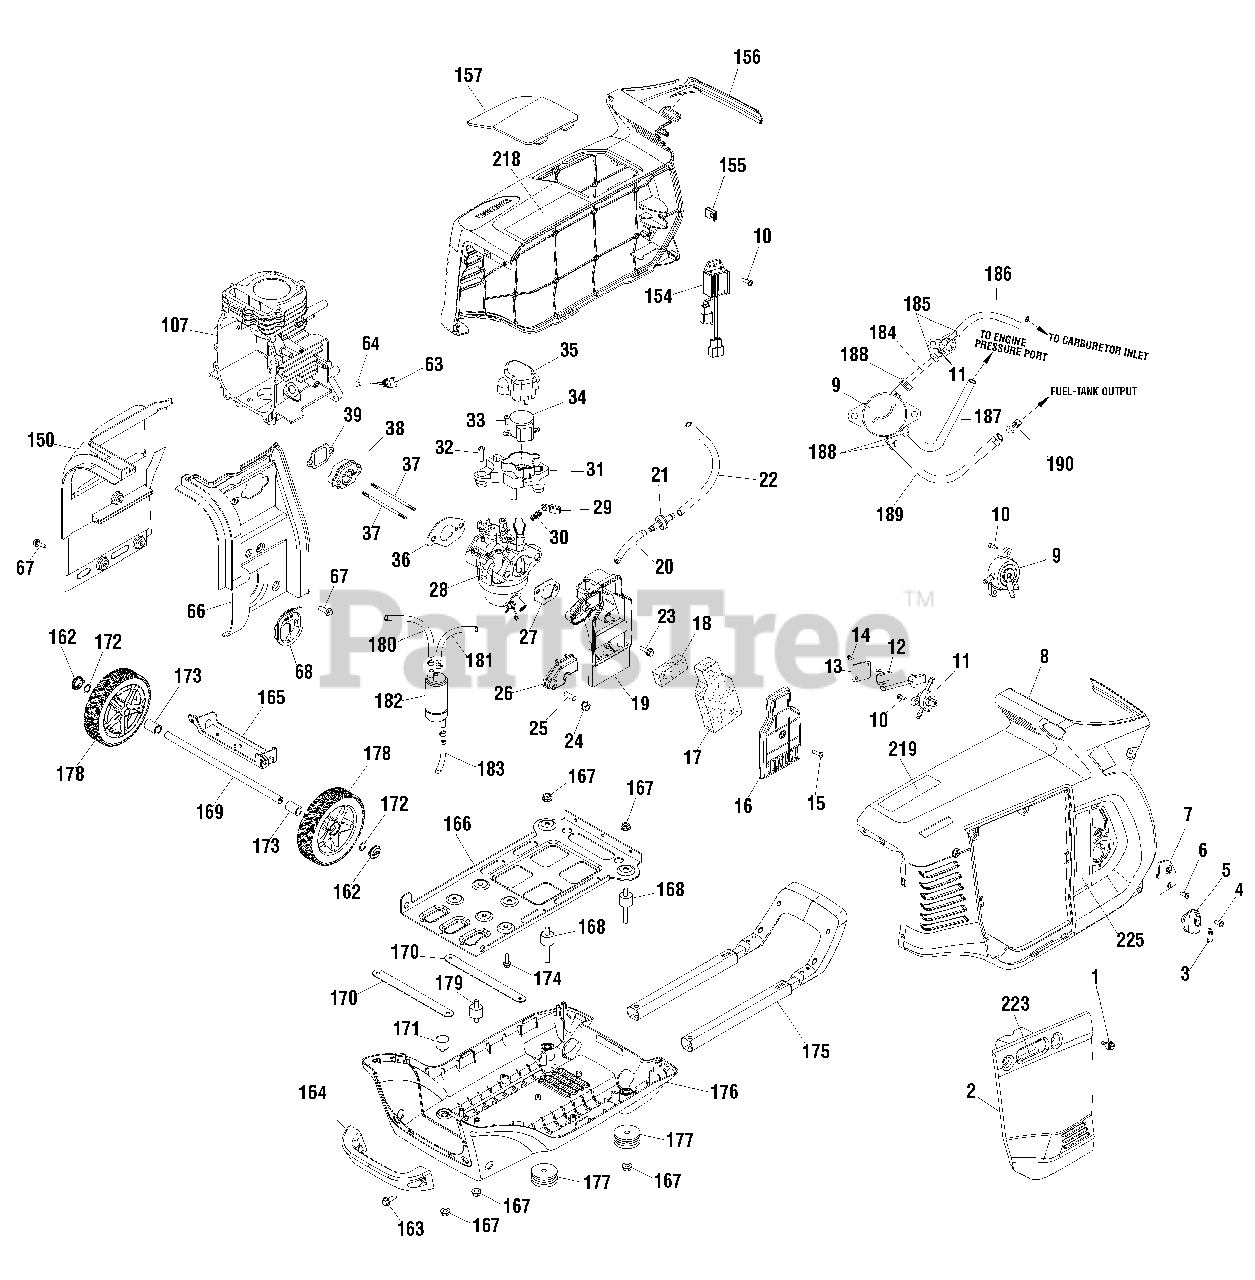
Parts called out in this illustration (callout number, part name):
4	SCREW
6	SCREW
10	SCREW
13	COVER-SWITCH
14	SCREW
16	COVER-AIR CLEANER
17	FILTER-A/C FOAM
18	FILTER-A/C FOAM
19	BASE-AIR CLEANER
23	BOLT-M5 x 12
24	NUT
25	SLEEVE
26	COVER-AIR CLEANER
27	GASKET-AIR CLEANER
29	ROD-THROTTLE
30	SPRING
32	SCREW
33	SCREW
34	MOTOR-STEPPER
66	DEFLECTOR
67	BOLT-M6 x 12
68	SEAL-RUBBER
107	CRANKCASE
150	DEFLECTOR
154	REGULATOR-VOLTAGE
155	NUT
157	COVER-SPARK PLUG
163	BOLT-M6 x 25
168	MOUNT-VIBRATION
171	MOUNT-VIBRATION
172	CLIP
174	BOLT-M8 x 16
177	MOUNT-VIBRATION
179	MOUNT-VIBRATION
185	CLAMP
188	CLAMP
